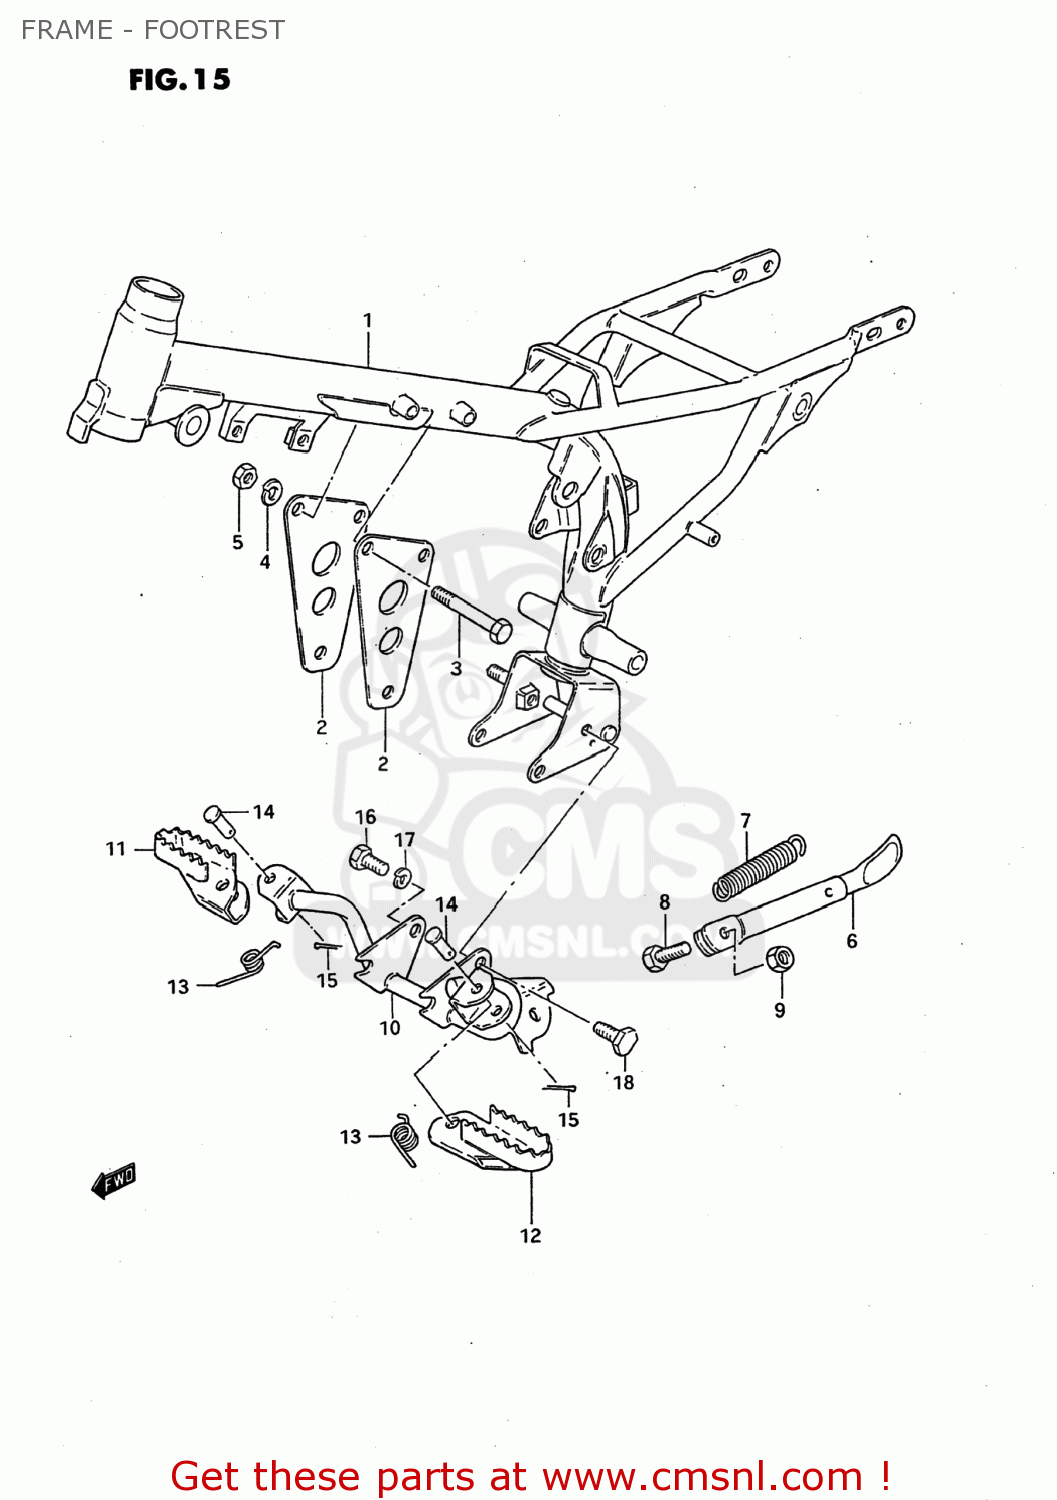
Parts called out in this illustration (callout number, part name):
1	FRAME
2	PLATE,ENG MTG
3	BOLT
4	LOCK WASHER
5	NUT
6	STAND,PROP
7	SPRING
8	BOLT 8X22
9	NUT
10	BAR,FR FOOTREST
11	FOOTREST,FR,R
12	FOOTREST,FR,L
13	SPRING
14	PIN
15	PIN 20X20
16	BOLT
17	LOCK WASHER
18	BOLT(8X14)
